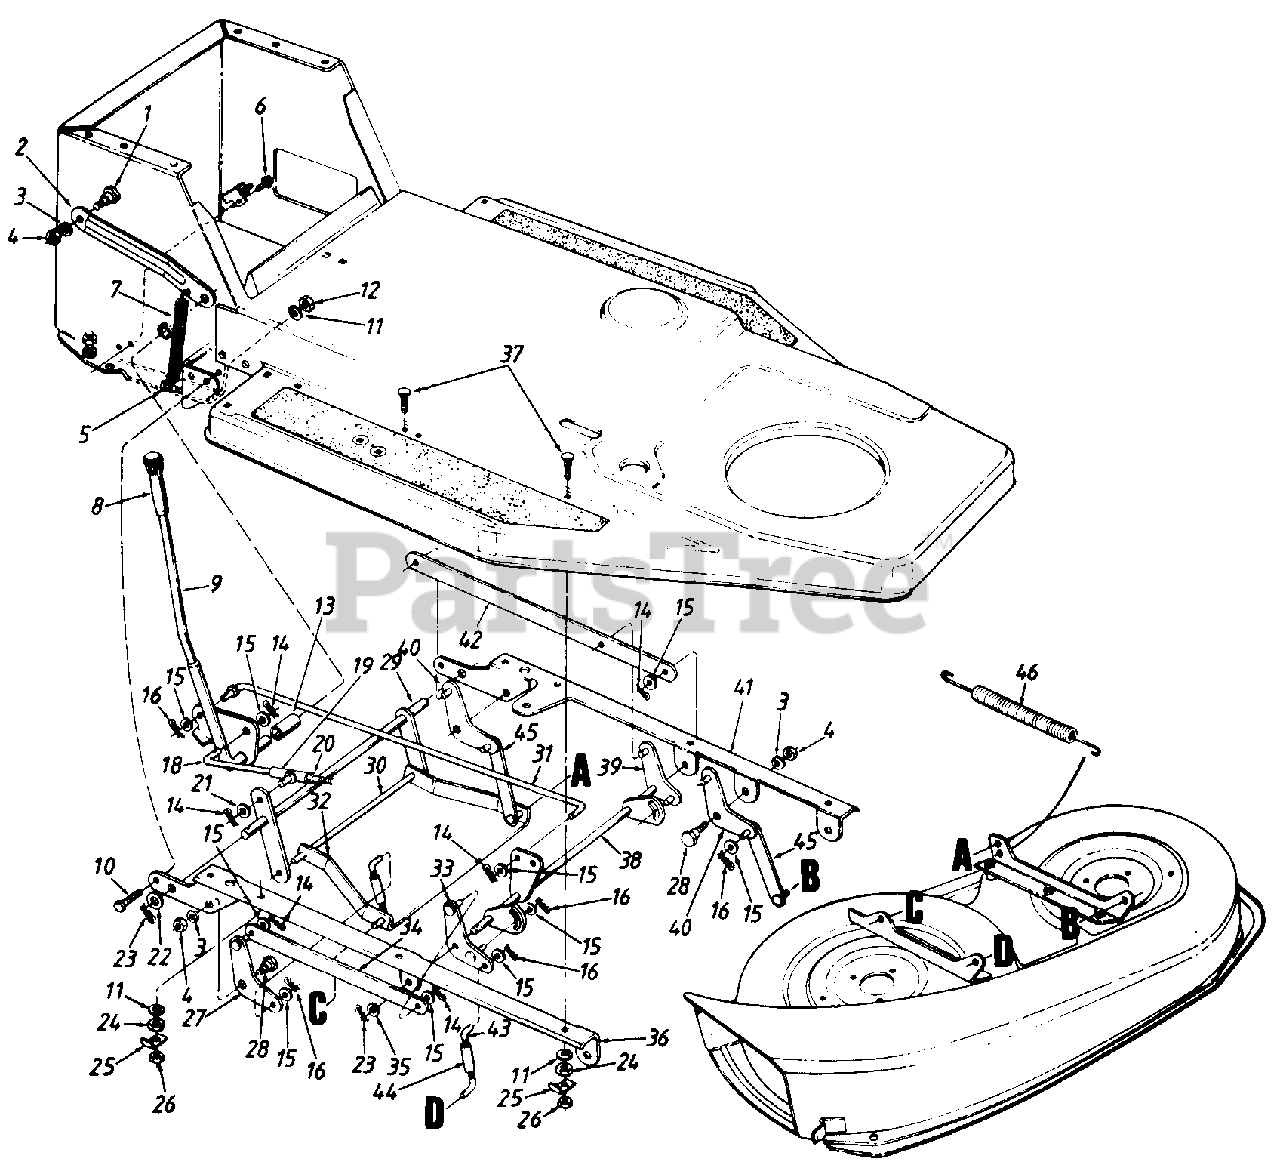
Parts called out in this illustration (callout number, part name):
1	Shld. Bolt .5" Dia. x .25" Lg.
4	Hex Nut 3/8-16 Thd.
5	Hex Bolt 1/4-28 x 1.25" Lg.
6	Hex Wash. Hd. TT-Tap Scr. 1/4-20 x .5" Lg.
9	Deck Lift Handle Ass'y.
10	Hex Wash. TT-Tap Scr. 5/16-18 x .62" Lg.
11	L-Wash. 5/16" I.D.
12	Hex Nut 5/16-18 Thd.
13	Nylon Sleeve Brg.
14	Cot-Pin 3/32" Dia. x .75" Lg.
15	Fl-Wash. 406n l.D. x .75" O.D.
16	Internal Cot-Pin 5/16" Dia.
18	Deck Engagement Rod
19	Pivot Sleeve Ass'y.
20	Hex L-Nut 3/8-16 Thd.
21	Thrust Washer .382" I.D.
22	Fl-Wash. .635" I.D. x 1.04 O.D.
23	Cot-Pin 1/8 Dia. x 1.25" Lg.
24	Hex Nut 5/16-24 Thd.
25	Harness Retainer
26	Hex Cent. L-Nut 5/16-24 Thd.
27	Deck Pivot Brkt. Ass'y.-R.H. Rear
28	Shld. Bolt .625n Dia. x .170" Lg.
31	Deck Lift Rod
32	Deck Stabilizer Brkt.
44	Adj. Lift Link Ass'y.
45	Deck Lift Link Ass'y.
46	Deck Spring 10.33n Lg.
